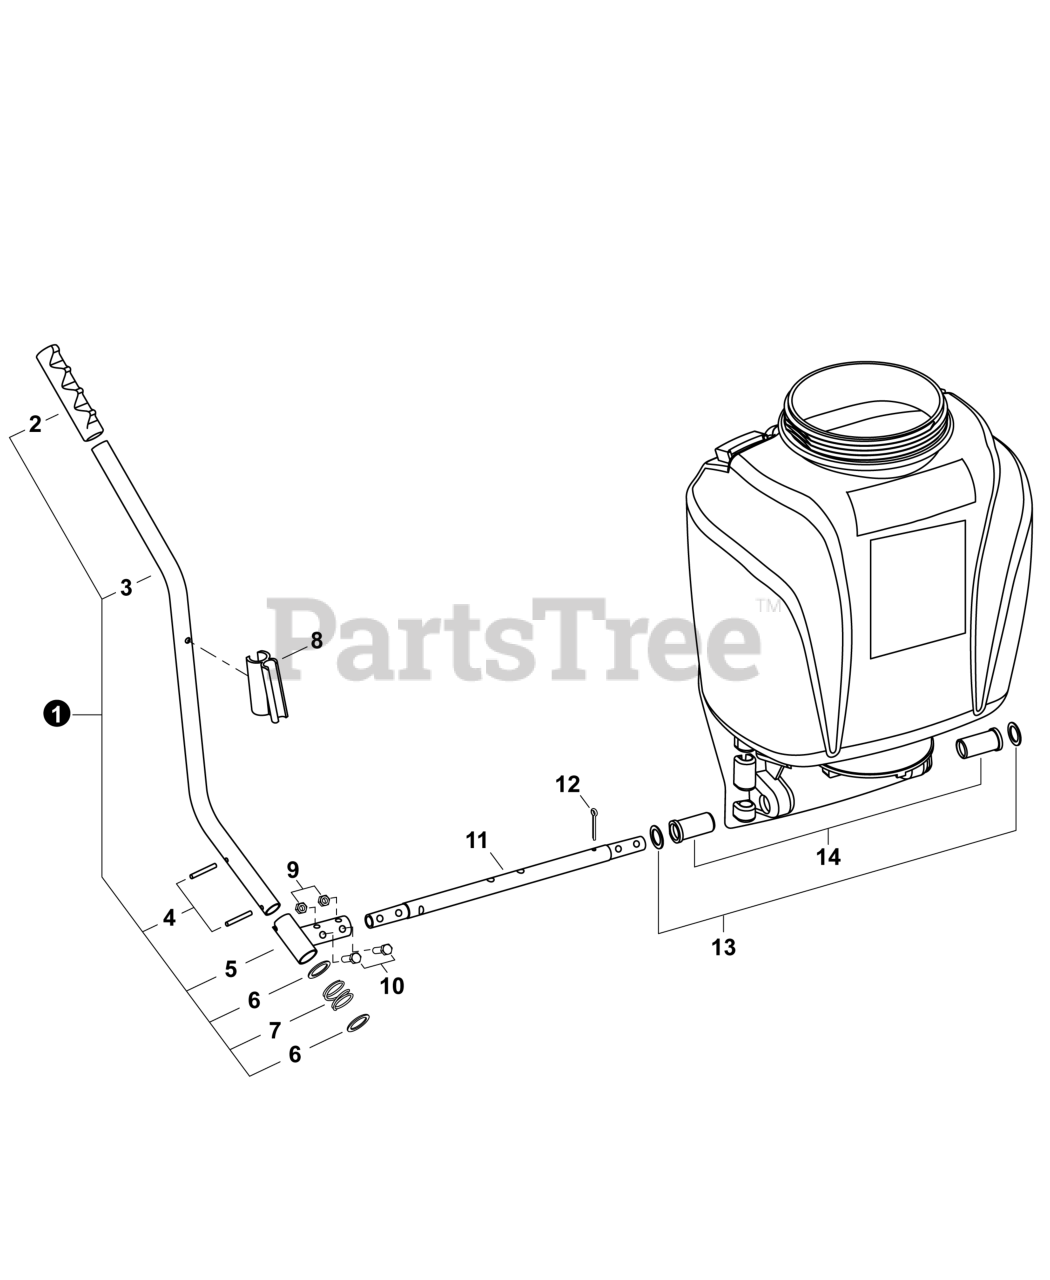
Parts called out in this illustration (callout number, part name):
1	LEVER KIT, PUMP
2	GRIP, LEVER
3	LEVER, PUMP
4	PIN, LEVER
5	BRACKET, LEVER
6	WASHER, LEVER
7	SPRING, LEVER
8	CLIP, METAL WAND
9	NUT, 5/16-18 NYLOC
10	BOLT 5/16"-18×1-1/4"
11	SHAFT, PUMP
12	PIN, SHAFT
13	WASHER, SHAFT
14	BUSHING, SHAFT
